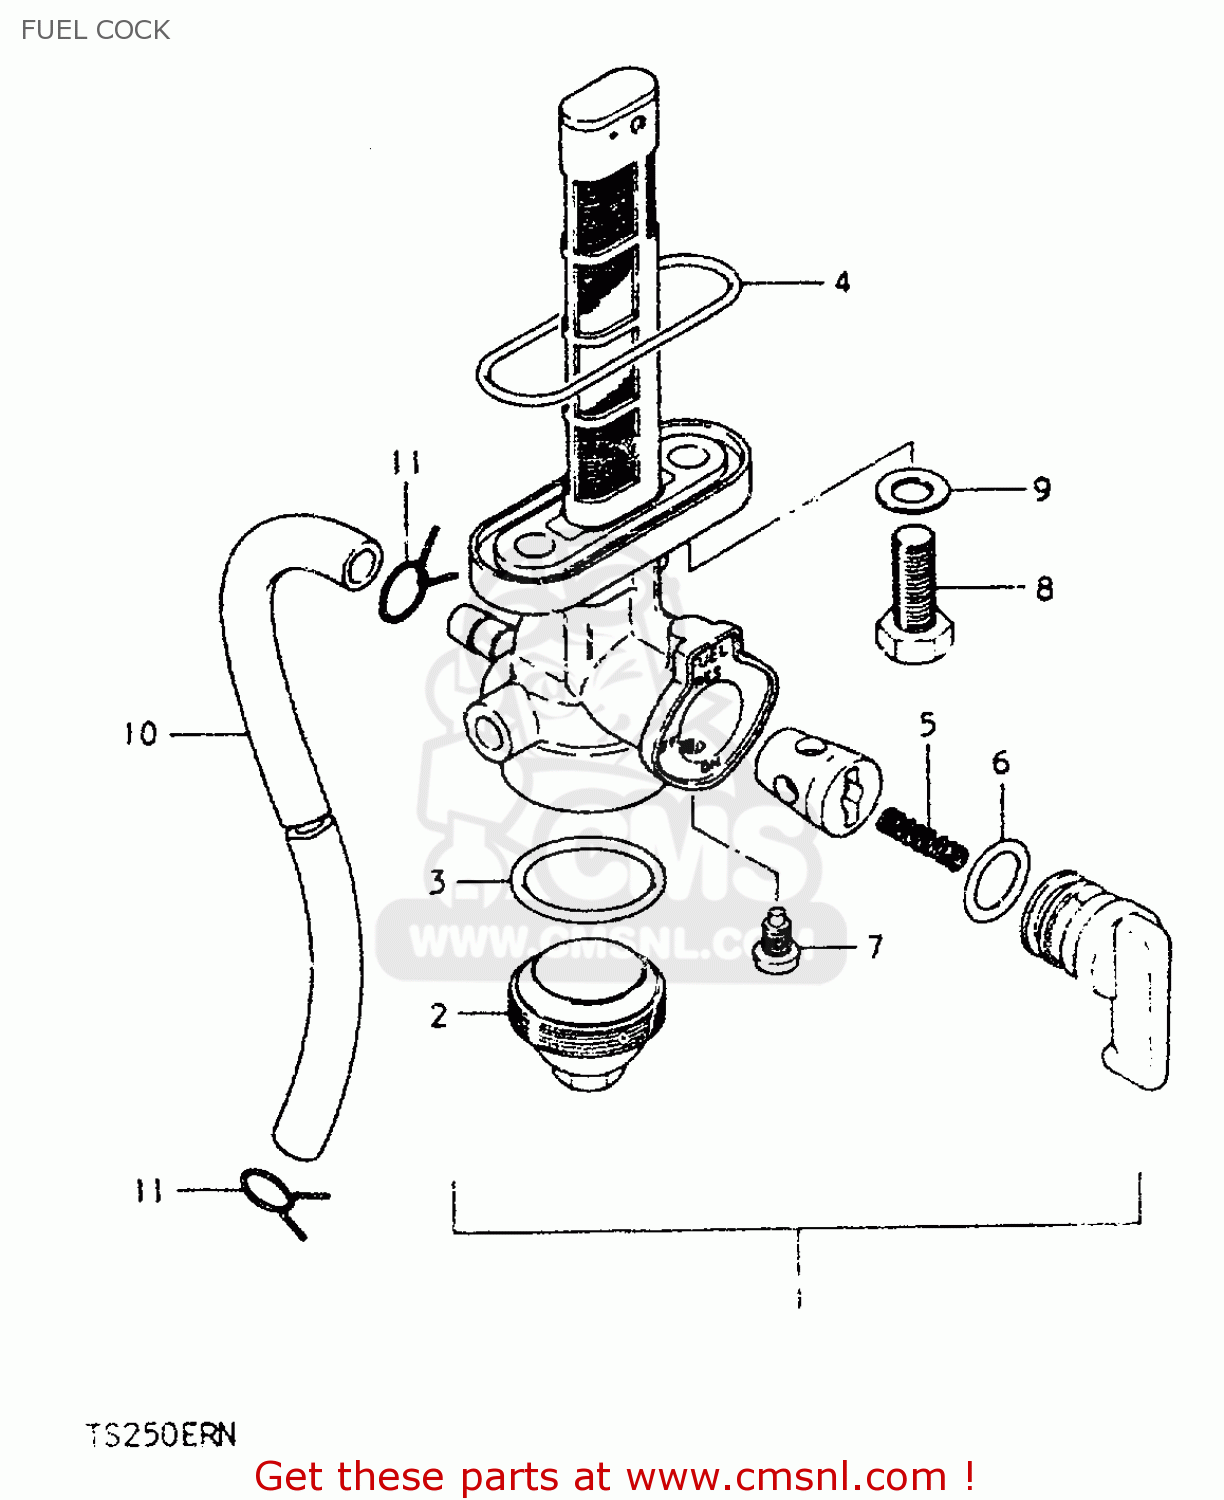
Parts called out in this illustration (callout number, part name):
1	COCK ASSEMBLY,FUEL
2	CUP,STRAINER
3	GASKET,FILTER (NAS)
4	O RING,FUEL COCK
5	SPRING
6	O-RING
7	SCREW
8	BOLT L:16
9	GASKET
10	HOSE
11	CLIP
